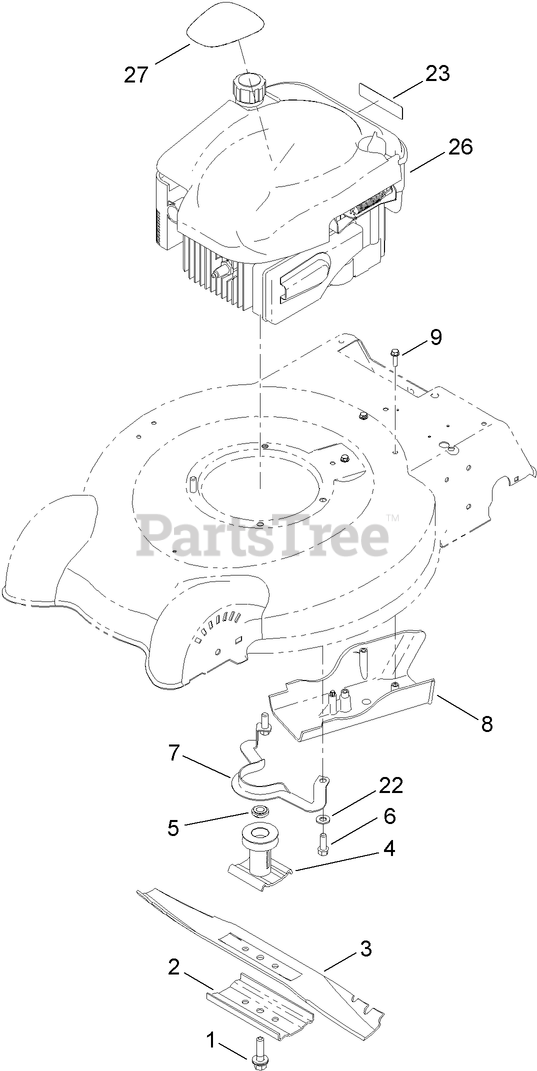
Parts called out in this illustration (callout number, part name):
1	BOLT-BLADE
2	SUPPORT-BLADE
4	DRIVER-BLADE
5	SPACER-DRIVER
6	SCREW-TAPTITE
8	COVER-BELT
9	SCREW-HWH
22	WASHER-FLAT
23	DECAL-ARRESTER, SPARK
27	DECAL-SHROUD
